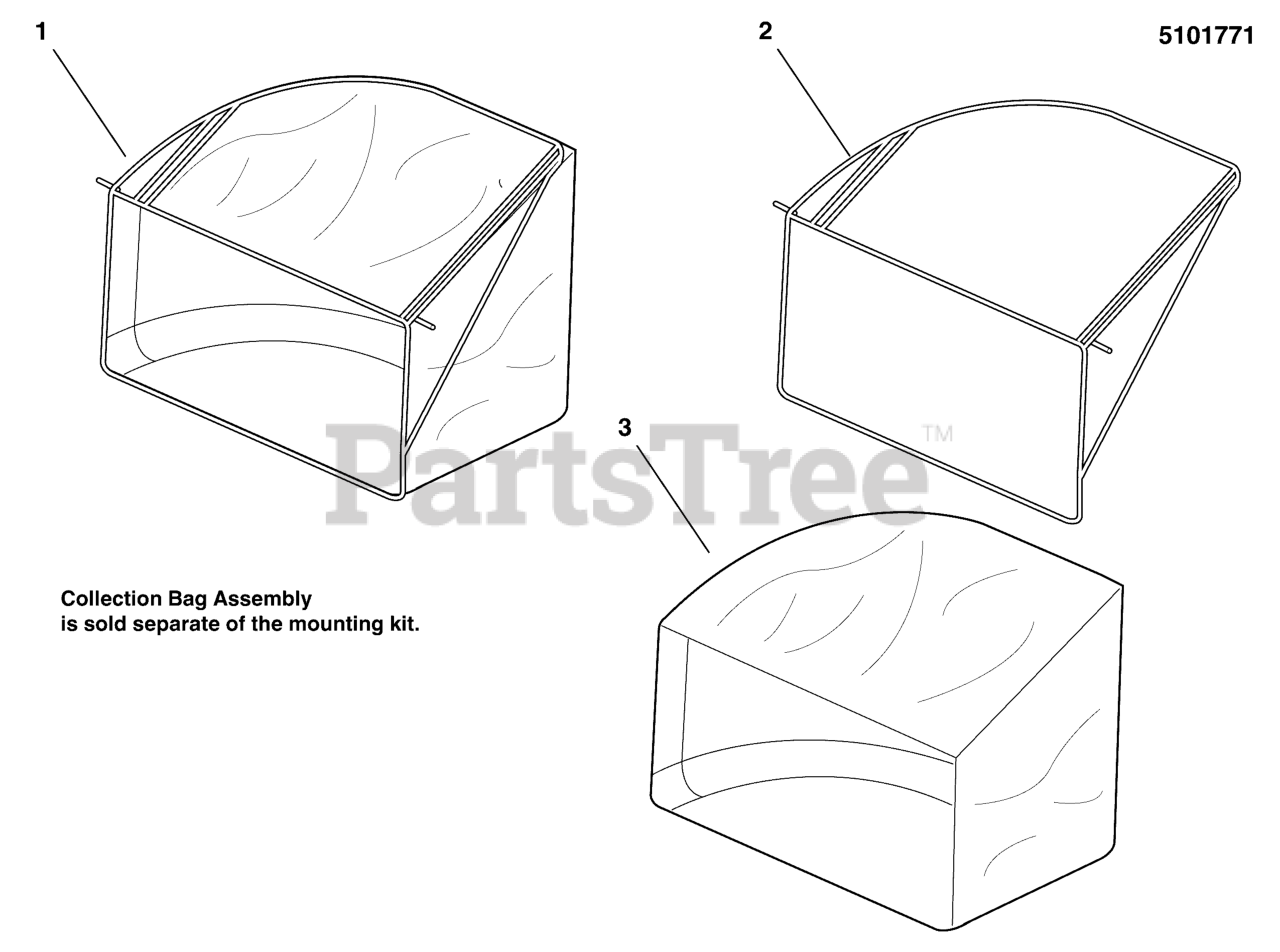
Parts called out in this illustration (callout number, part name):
1	COLLECTION BAG ASM, 3.75 BUSHEL - NET
2	SIDE CATCHER FRAME DUAL PURP.- FRA150000
3	3.75 BUSHEL BAG - 305 001 213
